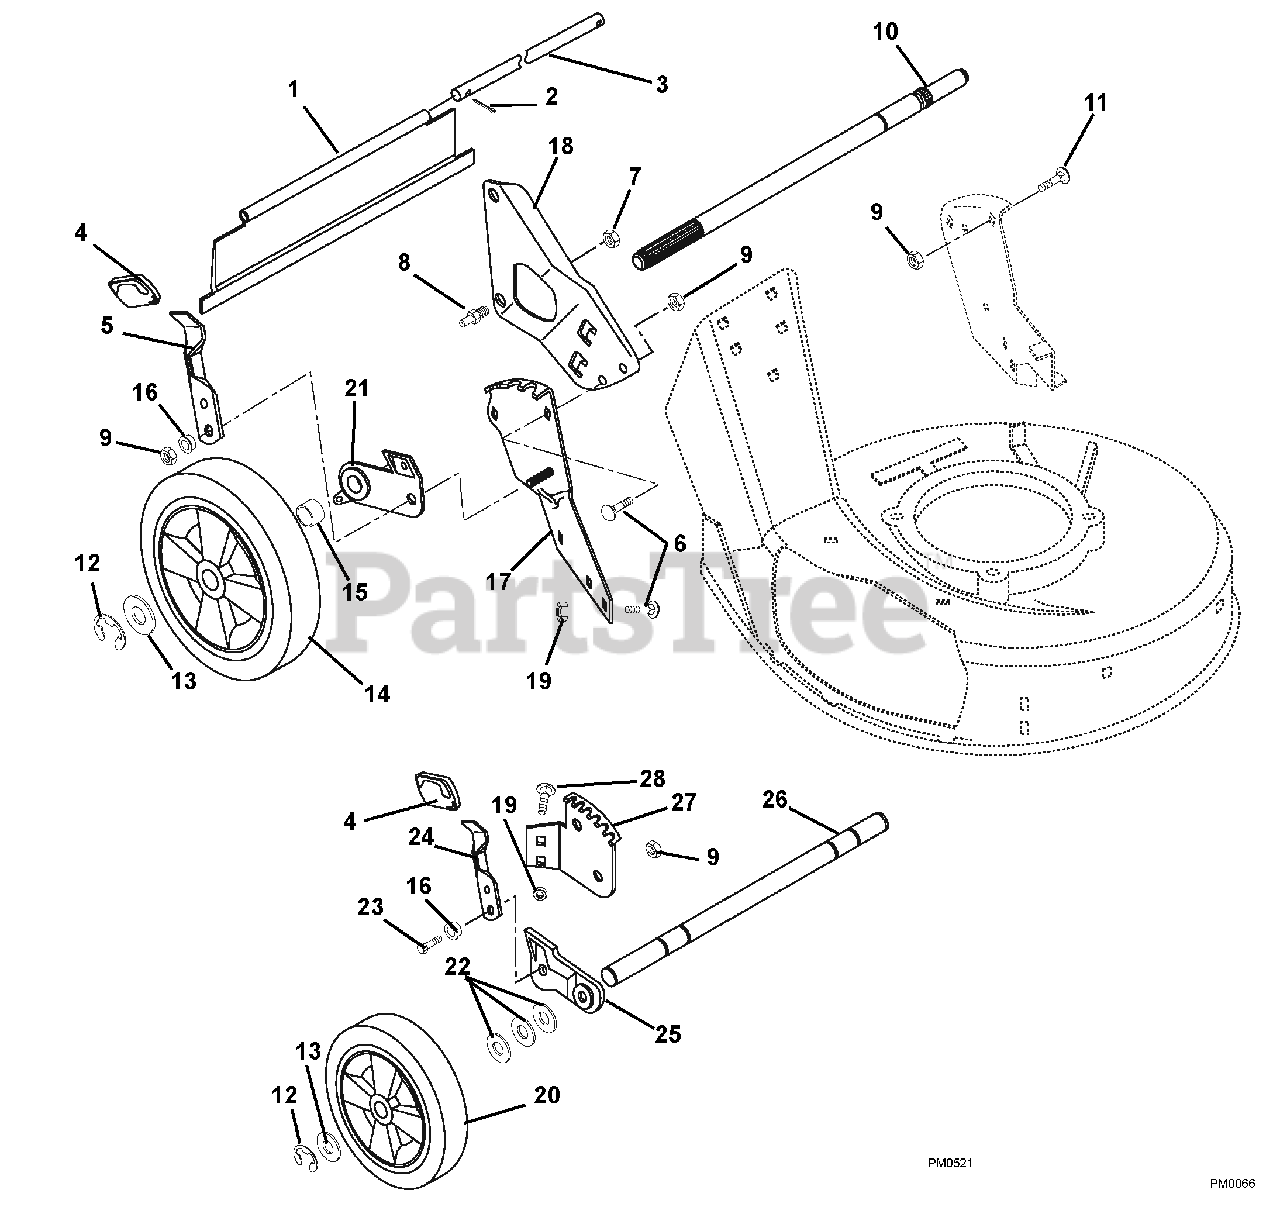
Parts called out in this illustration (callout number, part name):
1	REAR PROTECTIVE GUARD, S.P.
2	@PIN-CTR .06X.50 EXTPRSQCT YWZ
3	ROD
5	LEVER, HEIGHT ADJUSTMENT
6	@BLT-RHDSSQNK .31-18X.62 G5YZ
7	@NUT-LK-CTR .38-16 YWZC
8	HANDLEBAR STUD
9	@NUT-LK-TOP-FLG .31-18 YWZC
10	REAR AXLE,5/8 DIA
10	REAR AXLE-PUSH MOWER MM
11	BLT-RDHDSQNK .31-18X1.0 SHTYZ
12	RG-RTNG-EXT .500X.042 (E)
13	WSHR-FL-STL .505X.880X.072 YWZ
14	WHL, LH 10.50"
14	WHL, RH 10.50"
14	10 1/2 TIRE SKIN
14	TIRE, REAR 10X1.75 #6 GRAY
15	SPACER TUBE, SELF PROPEL
16	BSHG-FLG .32X.500X.344X.880
17	QUADRANT, REAR LH
17	QUADRANT, REAR RH
18	RH HANDLEBAR MTG. BRKT
18	LH HANDLEBAR MTG. BRKT
19	@NUT-LK-TOP-FLG .31-18 YWZC
20	WHL 7.50" .50 BORE, 1.50 HUB
20	TIRE, FRONT 7X1.50
21	REAR ADJUSTMENT BRACKET L.H.
21	REAR BRACKET & BEARING ASSY RH
22	WSHR-FL-STL .52X.827X.062 YWZC
23	@BLT-HEX .31-18X1.00 GR5 YWZC
24	FRONT HEIGHT ADJUSTMENT LEVER
25	LEFT ADJUSTOR BRACKET ASSEMBLY
25	RIGHT ADJUSTOR BRACKET ASSEMBL
26	FRONT AXLE
27	FRONT QUADRANT, LH
27	FRONT QUADRANT, RH
28	@BLT-RDHDSQNK .31-18X.50 G5YZ
